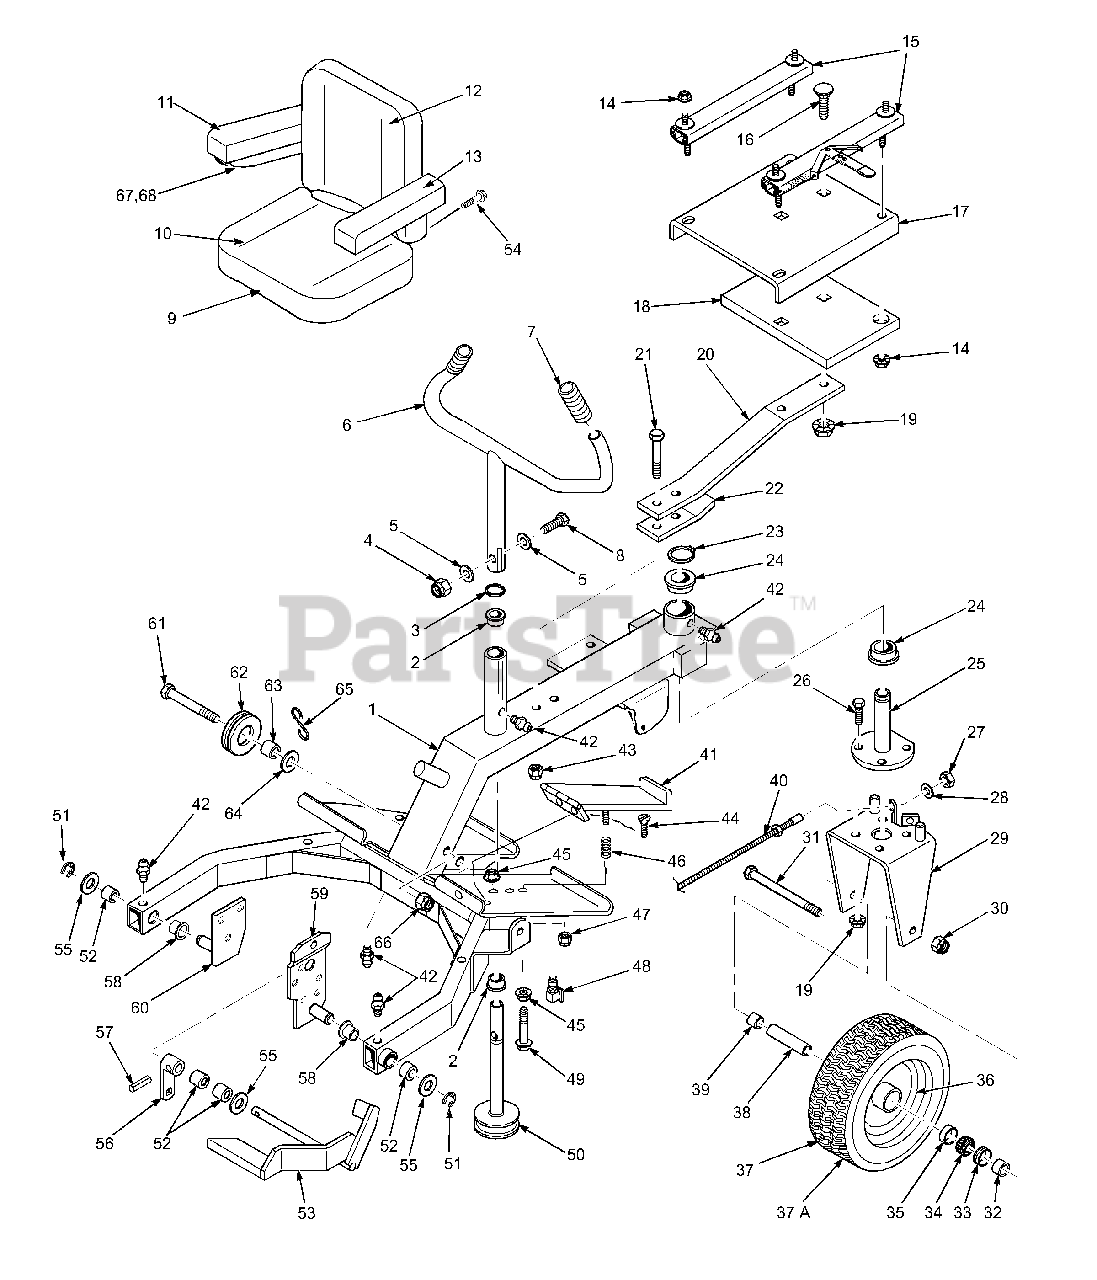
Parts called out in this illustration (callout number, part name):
1	Steering Frame
2	Bronze Bushing, 7/8 ID x 1.0 Flanged
3	Retaining Ring, 7/8 external
4	Hex Nut, Elastic Stop 5/16-18
5	Flat Washer, 5/16 (3/8 x 7/8 x 13 ga.)
6	Steering Handle
7	Grip
8	Bolt, Hex Hd., 5/16-18 x 1-3/4"
9	Seat Assy.
10	Cushion Assembly
11	Arm Pad - R.H.
12	Seat Back Cushion
13	Arm Pad - L.H.
14	Serr. Fl. HH. Nut, 5/16-18
15	Seat Adjuster Track
16	Bolt, RDHD Carr. 3/8-16 x 1-1/2 (52" & 61")
17	Seat Plate
18	Ballast, Seat Mount (72" cutter deck only)
19	Serr Fl. Hex Nut, 3/8-16
20	Seat Spring
21	Bolt, Hex Hd., 7-16-14 x 3-1/2"
22	Reinforcement, Seat Spring
23	Retaining Ring, 1-1/8" external
24	Bushing, Oilite - 1-1/8 ID x 1.0 Flanged
25	Rear Wheel Pivot
26	Bolt, Hex Hd., 3/8-16 x 1-1/4"
28	Lock Washer, 3/8 Internal Tooth
29	Rear Wheel Yoke
30	Hex Elastic Stop Nut, 5/8-11
31	Bolt, Hex Hd. 5/8-11 x 9"
32	Spacer, Rear Wheel, short
33	Seal, Grease
34	Bearing Cone
35	Bearing Cup
36	Rim Only
37	Rear Wheel Assy.
37A	Tire Only
38	Sleeve, Rear Wheel
39	Spacer, Rear Wheel
40	Cable, Steering
41	Pedal, Foot Safety Switch
42	Grease Fitting
43	Hex Elastic Stop Nut, 7/16-14
44	Screw, Phillips flat hd #10-32 x 3/4"
45	Serr. Fl. Hex Nut, 1/4-20
46	Spring, Foot Safety Switch
47	Hex Nut, Elastic Stop Lock, 1/4-20
48	Switch, Foot Safety
49	Bolt, Hex Hd., 1/4-20 x 1-3/4"
50	Steering Shaft
51	Retaining Ring 3/4 Ext. "E"
52	Bushing, Oillube - 3/4 ID x 1.0
53	Foot Pedal
54	Screw w/washer, 1/4-20 x .75"
55	Flat Washer, 3/4 x 1-1/4 x 16 Ga.
56	Foot Pedal Arm
57	Pin, Drive Lock 3/16 x 1-1/4"
58	Bushing, oillube - 3/4 x .50 Flanged
59	Sulky Mtg. Brkt. L.H.
60	Sulky Mtg. Brkt. R.H.
61	Bolt, Hex Hd., 1/2-13 x 5-1/2"
62	Pulley, Winch Cable
63	Bushing, Oillube - 1/2 ID x .56
64	Flat Washer, 1/2 (.562 x 1.375 x .109)
65	Retainer, Winch Cable
66	Hex Elastic Stop Nut, 1/2-13
67	Arm Rest Bracket, Left Hand
68	Arm Rest Bracket, Right Hand
